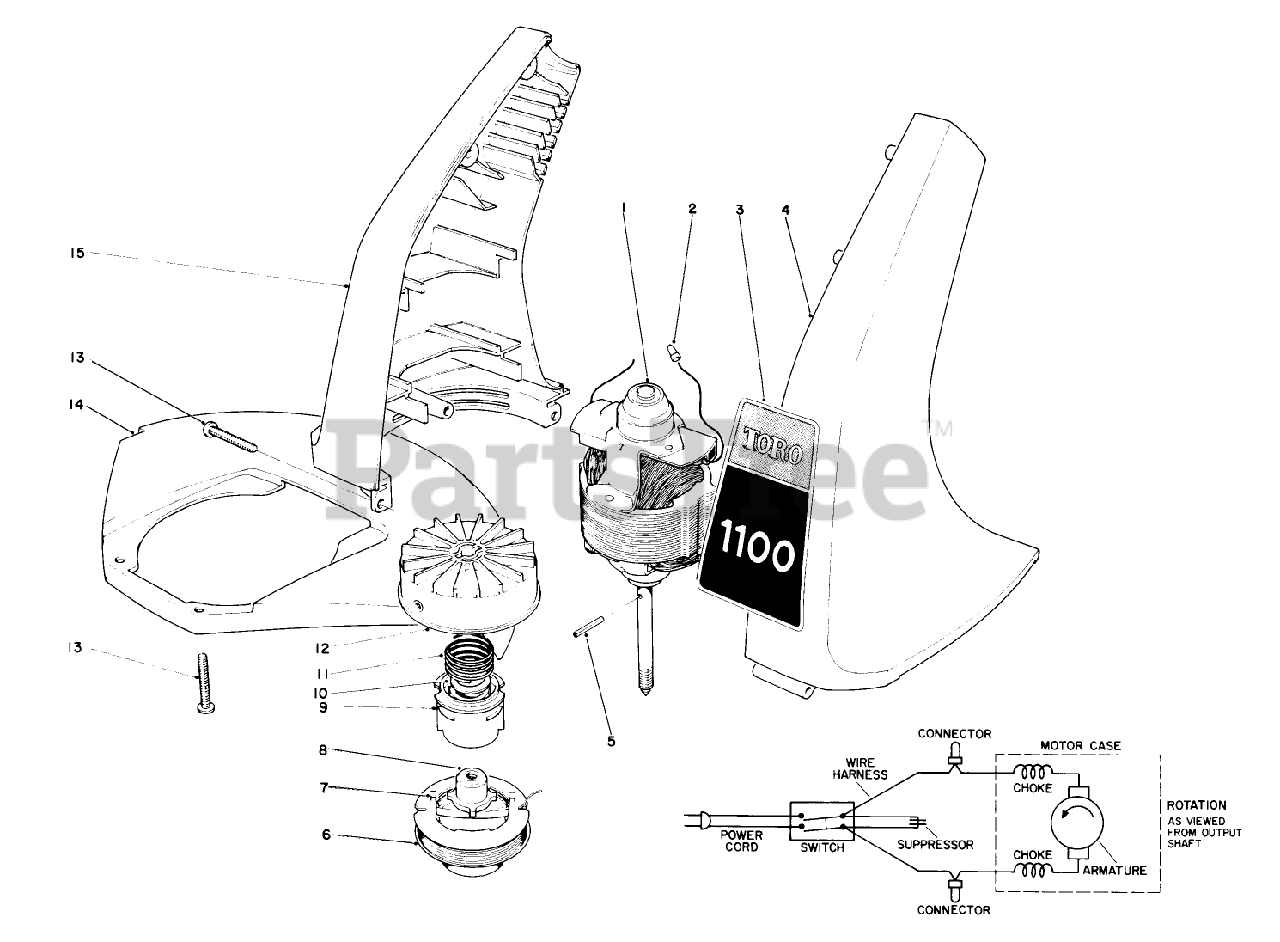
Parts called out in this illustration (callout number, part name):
1	Motor (220V)
2	Wire Connectors
3	1100 Decal
4	Housing-Left Hand
5	COIL PIN
6	Prewound Spool
7	SADDLE-SPOOL CAP
8	Driver
9	SPOOL CORE
10	WASHER-FLAT
11	SPRING COMPRESSION
12	DRUM W/EYELET
13	Screw
14	Shield
15	HOUSING-RH-INT'L
